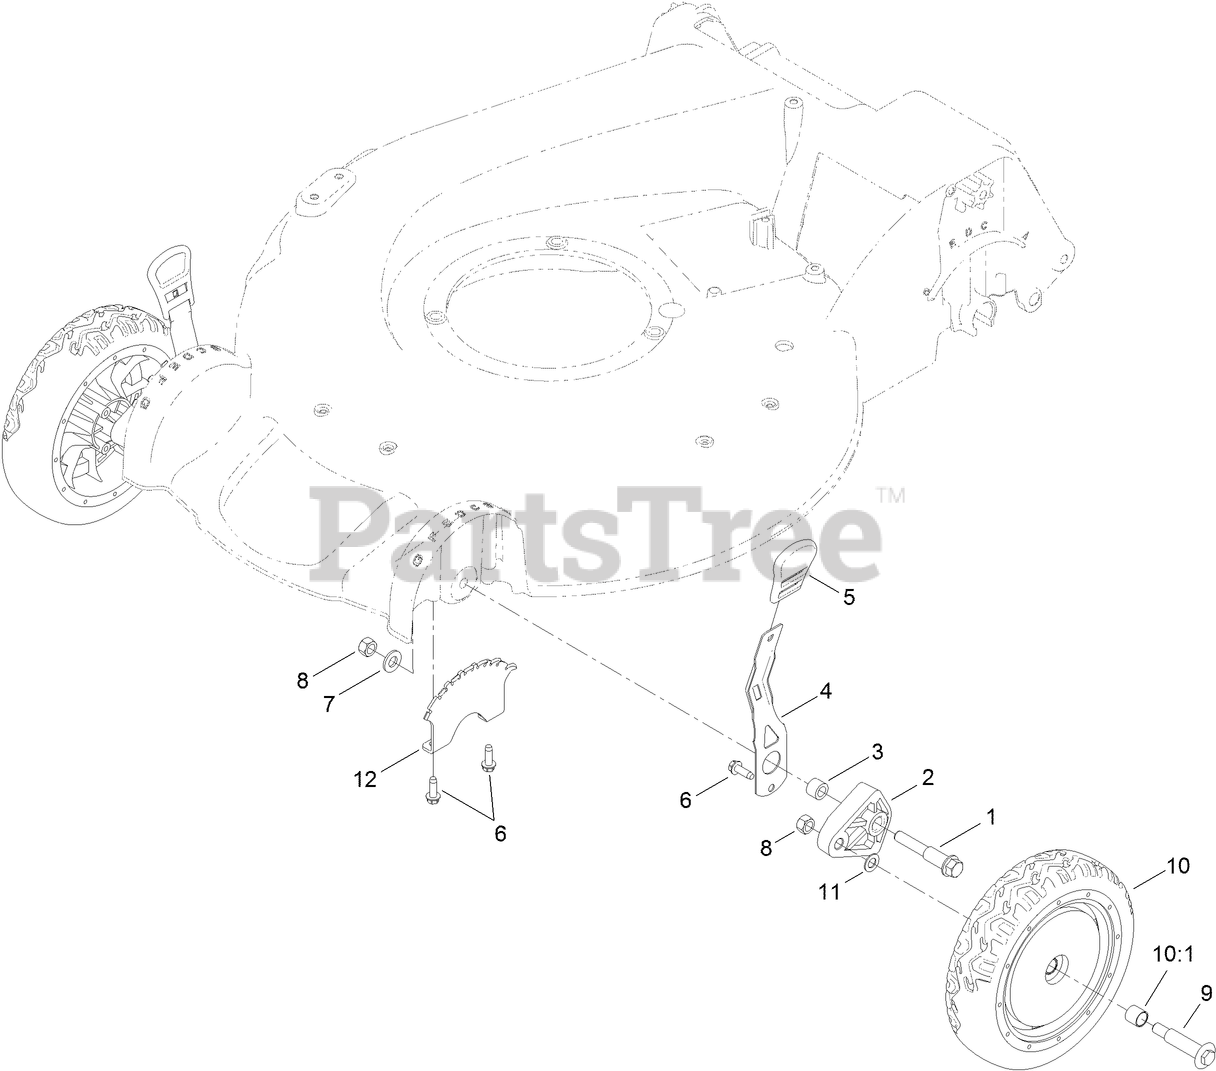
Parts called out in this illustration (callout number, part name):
1	SCREW-SHOULDER
2	ARM-PIVOT
3	SPACER-WHEEL
4	ARM-SPRING
5	KNOB-HOC
6	SCREW-HWHTF
7	WASHER-FLAT
8	LOCKNUT
9	BOLT-SHOULDER
10	8 INCH WHEEL ASM
10:1	BUSHING
11	WASHER
12	PLATE-HOC
